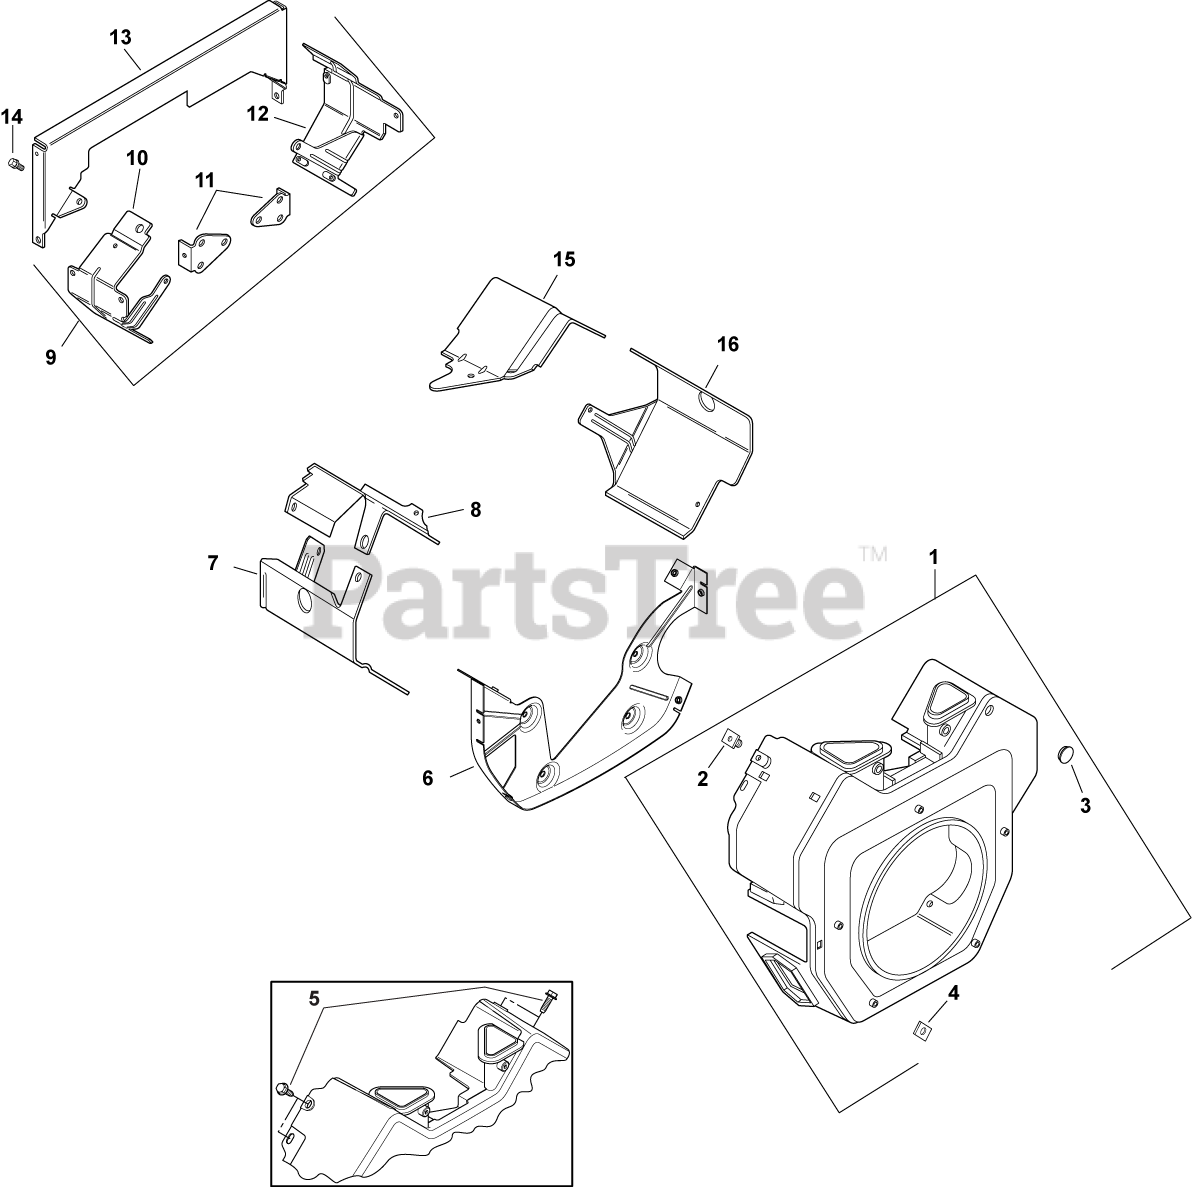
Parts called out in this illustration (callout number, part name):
2	NUT, PLASTIC (KM)-USE 25 100 37-S
3	PLUG, BUTTON 1/2
4	NUT, PLASTIC
5	SCREW,FLG THD FRM M6X1.0X16-(#25086397S)
6	PLATE, BACKING #2 SIDE-USE 24 146 59-S
7	BAFFLE,VALLEY #2SIDE(KM)-USE 24 063 88-S
8	BAFFLE,VALLEY #2SIDE(KM)-USE 24 063 70-S
9	KIT, "Q"DUCT"
10	BAFFLE, DUCTED AIR-OIL FILTER
12	BAFFLE, DUCTED AIR-STARTER
13	PLATE, BACKING
14	SCREW, FLG M6X1.0X10
15	BAFFLE, VALLEY (CH)-USE 24 063 93-S
16	BAFFLE, RIGHT BARREL-USE 24 063 85-S
M-551016-S	SCREW, HVY FLG M5X.8X16
